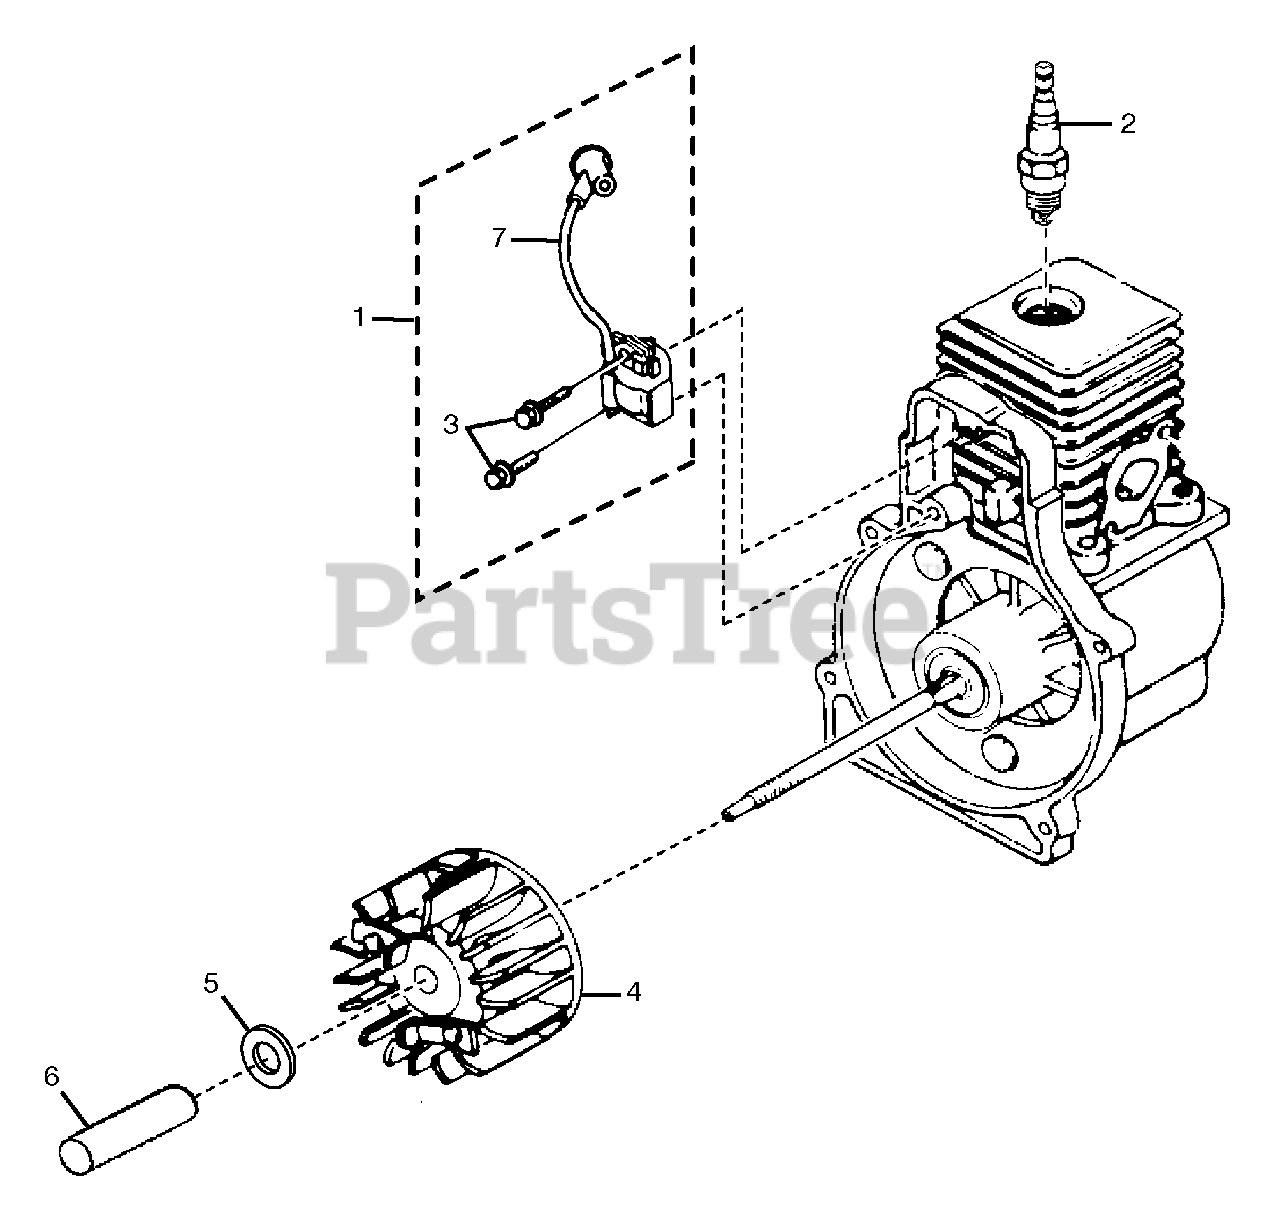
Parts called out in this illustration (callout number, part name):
1	IGNITION KIT WITH MODULE
2	SPARK PLUG
3	SCREW (8-32 x 1 in TORX PAN HD)
4	ROTOR AND STARTER PAWLS
5	FLAT WASHER
6	FAN SPACER
7	IGNITION MODULE
